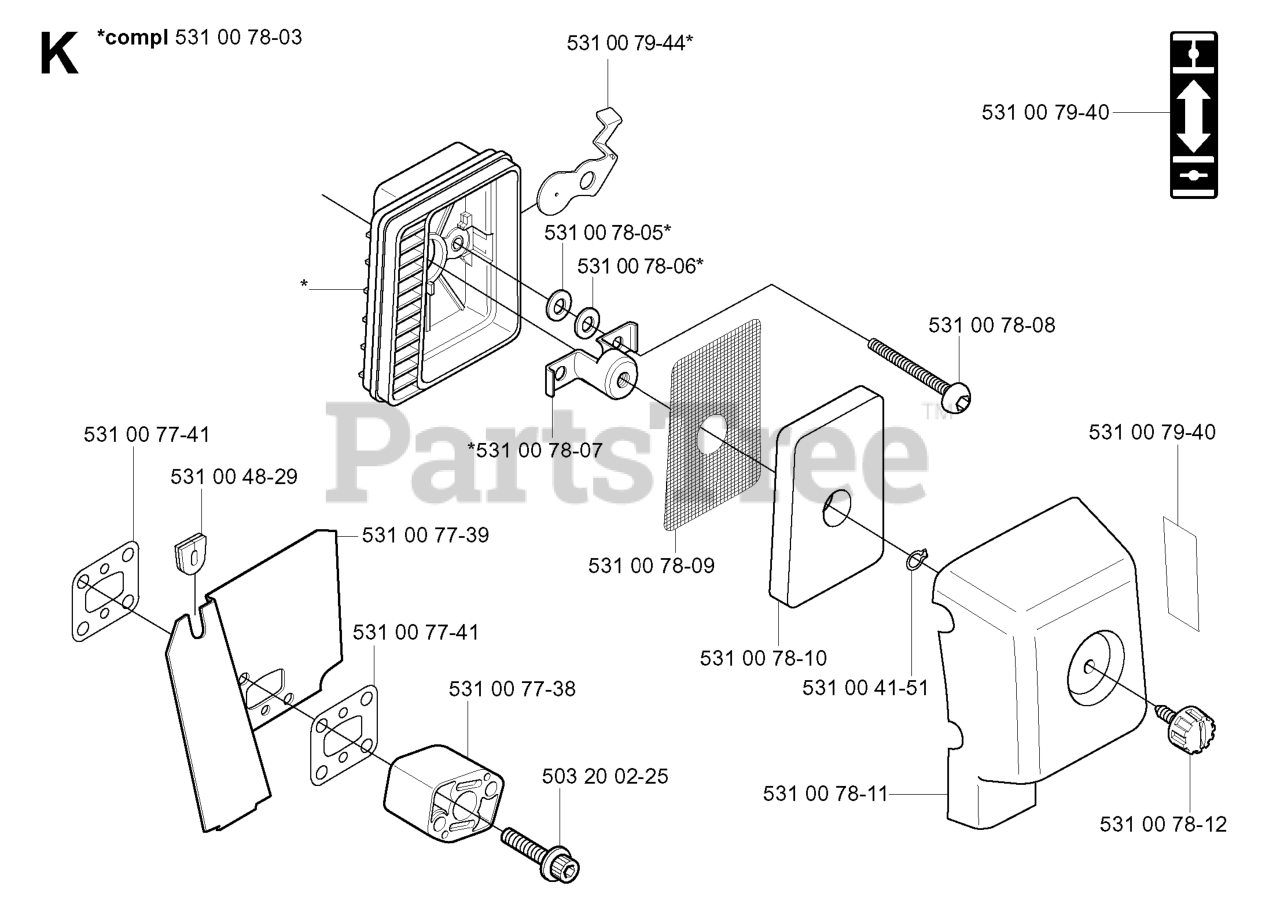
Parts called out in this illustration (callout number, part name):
1	DECK W/DECALS, RZ 30 ORG
2	WASHER-SPACER
3	KEEPER, BELT MANDREL, BLACK
4	PULLEY.MANDREL.5.0.PD.38"
5	BOLT.WASHER.ASM.7/16-2
6	BLADE.MOWER.BAGGING.30"
7	PULLEY.IDLER.FLAT.46.PR.DR.
8	BEARING, BALL
9	SPACER.RETAINER
10	KEEPER, BELT, BLACK
11	SPRING RETURN
12	WASHER 3/8 X 3/4 X .187 TK
13	MANDREL GREASABLE
14	WASHER HEAD SCREW
15	BLT 3/8-16X1-3/4 WHIZLK ZN SP
16	NUT 3/8-16 HEX FLG NYLOC ZD
17	BOLT 3/8-16 X 1 1/2 ZINC CLEAR
18	WASHER 3/8 FLAT
19	SHIELD.DEFLECT.MWR.30S.BLACK
20	TORSION SPRING
21	LOCKNUT - 9/16
22	HINGE ROD
23	PUSH NUT
24	BELT, 100" EL
25	ARM, REAR DECK SUSP, BLK
26	SB 3/8-16 X 3/8 SKT HD ZD
27	PORT.WASHOUT
28	BOLT 1/4-20 X 1/2 HWST
29	GUIDE, BELT
30	NUT 3/8-16 NYLOC
31	LINK LIFT SUSP. FRONT MOWER
33	7/16-14 HEX NUT W/NYL RING ZD
34	WASHER 1/2" FLAT
35	HAIRPIN #4
36	SPINDLE WASHER
37	ARM, IDLER, BLACK
38	ARM, LH BRAKE
39	REPL BY 532 1467-63
40	HCS 3/8C X 1 1/2
41	SCREW- 1/4-20 X 5/8
42	RHSNB 3/8-16 X 4 GR5 ZD
43	WASHER 7/16 FLAT ZD
44	SPACER .39 ID X 2.25
45	PULLEY, IDLER RAKE & ZTR
46	COUPLING.QUICK CONNECT
47	BRKT.DEFLECTOR.38"2005+
48	CARRIAGE BOLT 5/16C X 5/8"
49	5/16-18 NYLOC FLANGE NUT
50	NUT.1/4-20.HEX.NYLOC.ZD
51	COVER, PULLEY, BLACK
52	WASHER 3/8 X 3/4 X .187 TK
